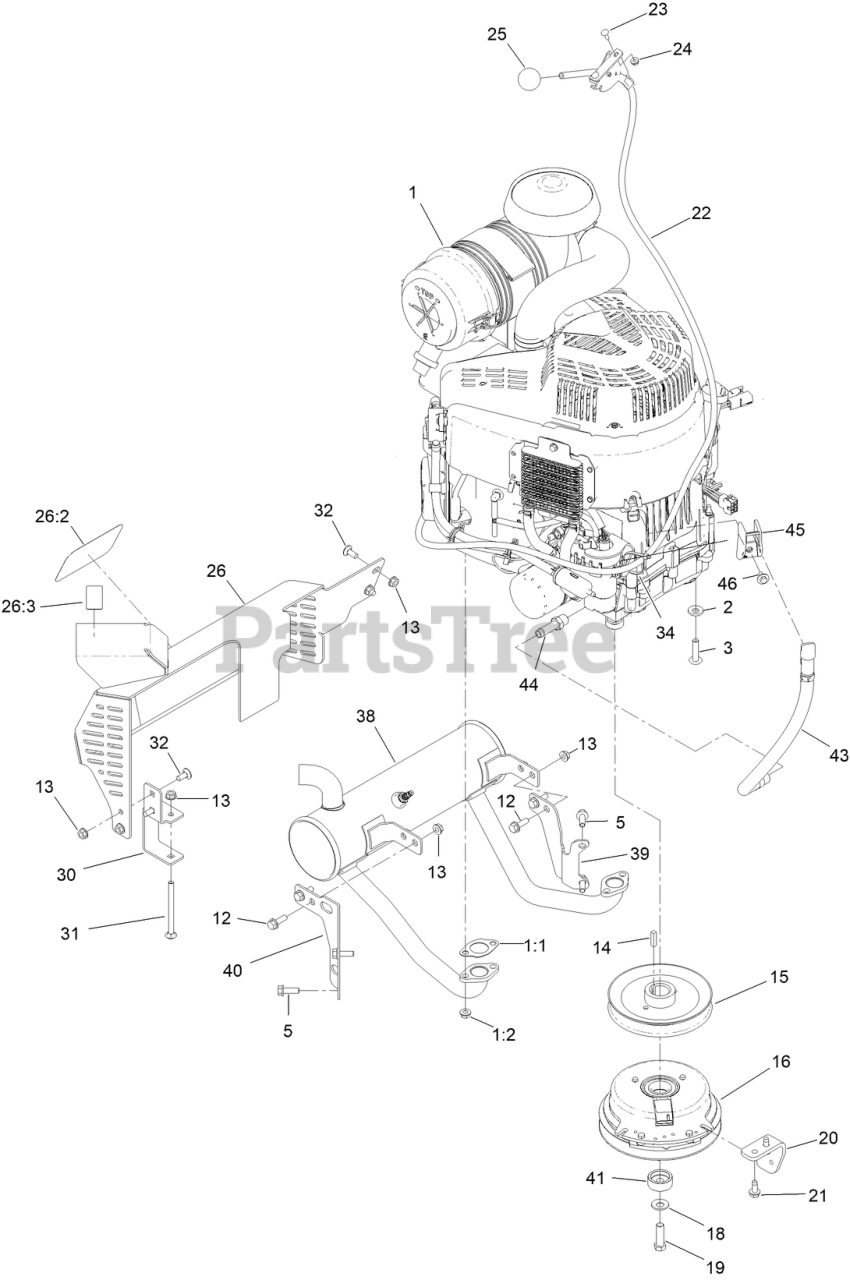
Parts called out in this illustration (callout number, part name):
1	VANGUARD 810CC BASCO ENGINE
1:1	GASKET, EXHAUST
1:2	EXHAUST NUTS
2	WASHER-BELLEVILLE
3	SCREW-BHTF
5	SCREW-HHF
12	SCREW-HHF
13	NUT-HF
15	PULLEY
16	CLUTCH
18	WASHER-SPRING
19	SCREW-HH
20	STOP-CLUTCH
21	SCREW-HWHTF
22	THROTTLE ASM
23	BOLT-CARR
24	NUT-LOCK, FLANGE
25	KNOB-BALL
26	MUFFLER GUARD ASM
26:2	DECAL
26:3	DECAL-HOT SURFACE
30	BRACKET-MOUNTING, GUARD
31	SCREW-CARR
32	SCREW-CARR
34	TIE-CABLE
38	GS MUFFLER
39	BRACKET-MUFFLER, REAR
40	BRACKET-MUFFLER, FRONT
41	SPACER-CLUTCH
43	OIL DRAIN HOSE ASM
44	FITTING-OIL DRAIN
45	BRKT-OIL DRAIN HOSE
46	BOLT-HEX, OIL DRAIN BRKT
